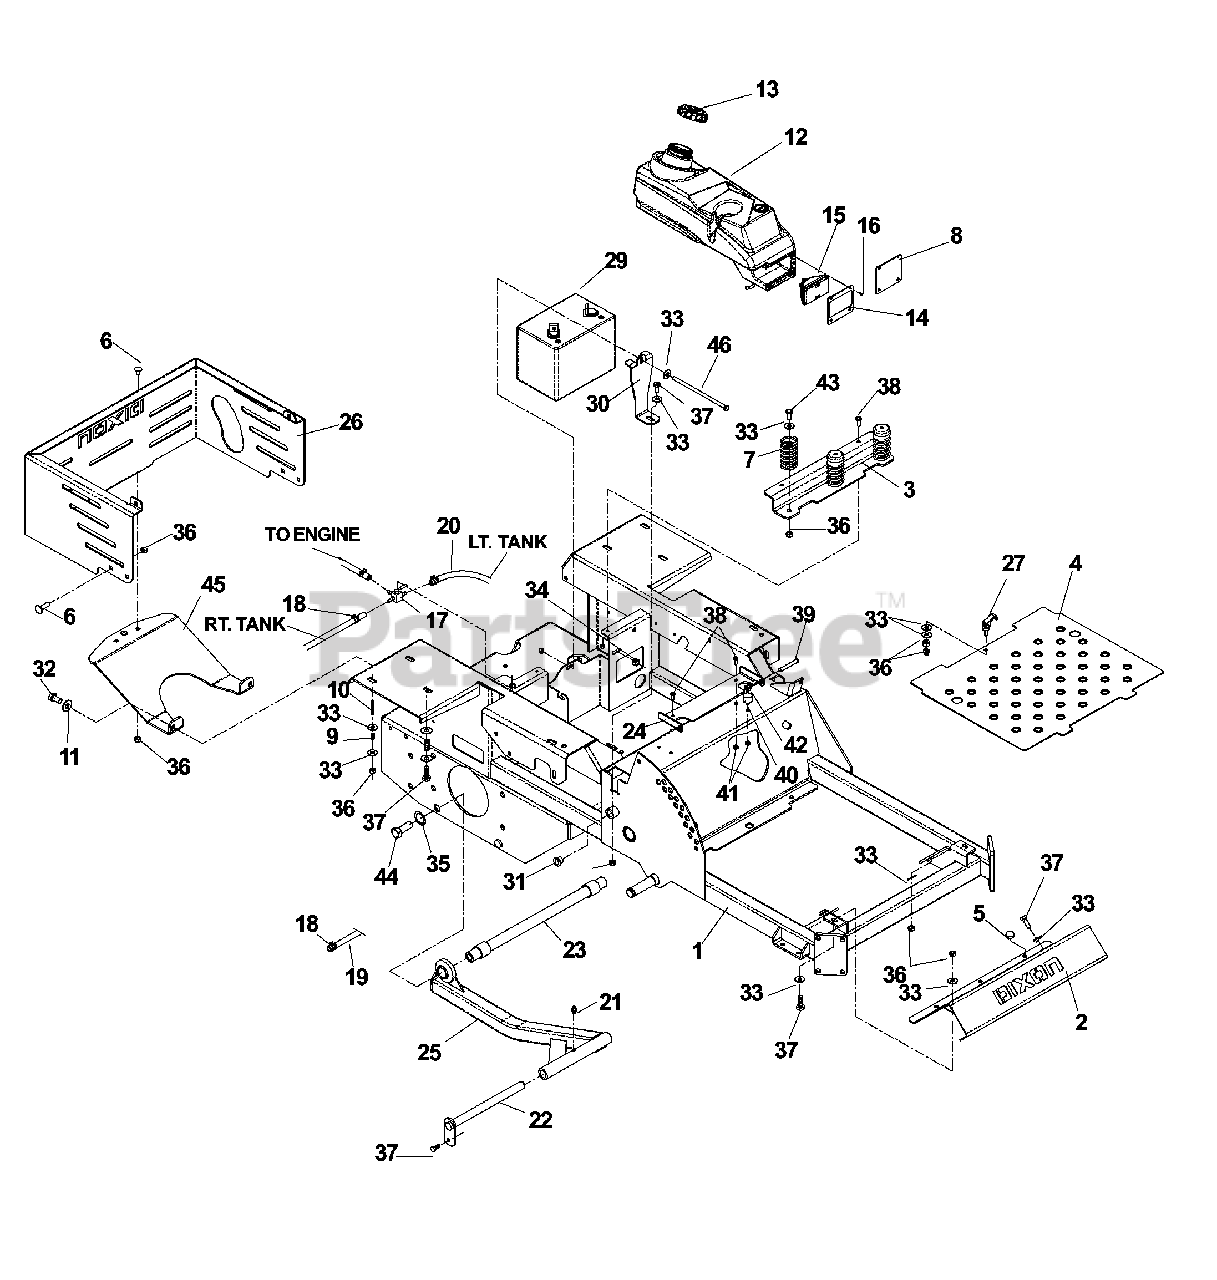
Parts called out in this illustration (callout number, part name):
1	FRAME W/DECALS
2	FOOT REST
3	SPRING MOUNT
4	PLATE, FOOT-W/DECALS
5	GROMMET, BUMPER
6	BOLT 5/16C X 3/4" CARRIAGE
7	SEAT SPRING
10	STUD, 5/16C
11	WASHER 3/8 FLAT
12	TANK, FUEL, LT
13	FUEL CAP ANTI-SPLASH
14	PLATE LIGHT
15	LIGHT
16	SCR #10-24 X 3/8 SKT HD BLK OX
17	FUEL VALVE
18	HOSE CLAMP
19	FUEL LINE 24"
20	FUEL LINE 34"
21	ZERK
22	PIVOT PIN
23	STRUT MOUNT WELDMENT
24	PLATE, MOUNT, SEAT
25	STRUT, RIGHT
26	GUARD, REAR W/DECALS
27	LATCH.SWELL.ACTION
28	5/16-18 NYLOC FLANGE NUT
29	BATTERY, 12 V 330 AMP TBR
30	BRKT, HOLD DOWN, BATTERY
31	BUSHING
32	HCS 3/8C X 1
33	WASHER 5/16 FLAT
34	NUT 5/16C CENTERLOCK
35	LOCKWASHER 5/8
36	NUT 5/16 NYLOC
37	HCS 5/16C X 1
38	HCS 1/4C X 3/4 HCS
39	SCREW 3/8C X 2 3/4 HEX CAP
40	STUD/PLATE MOUNT
41	NUT 1/4-20 NYLOC
42	NUT 3/8-16 NYLOC
43	SCREW 5/16C X 1 HEX CAP
44	HCS 5/8C X 2 GR.5
45	PLATE, SKID
46	HCS 5/16-18 X 6 GR 5 ZD
47	WASHER 1/4 FLAT
